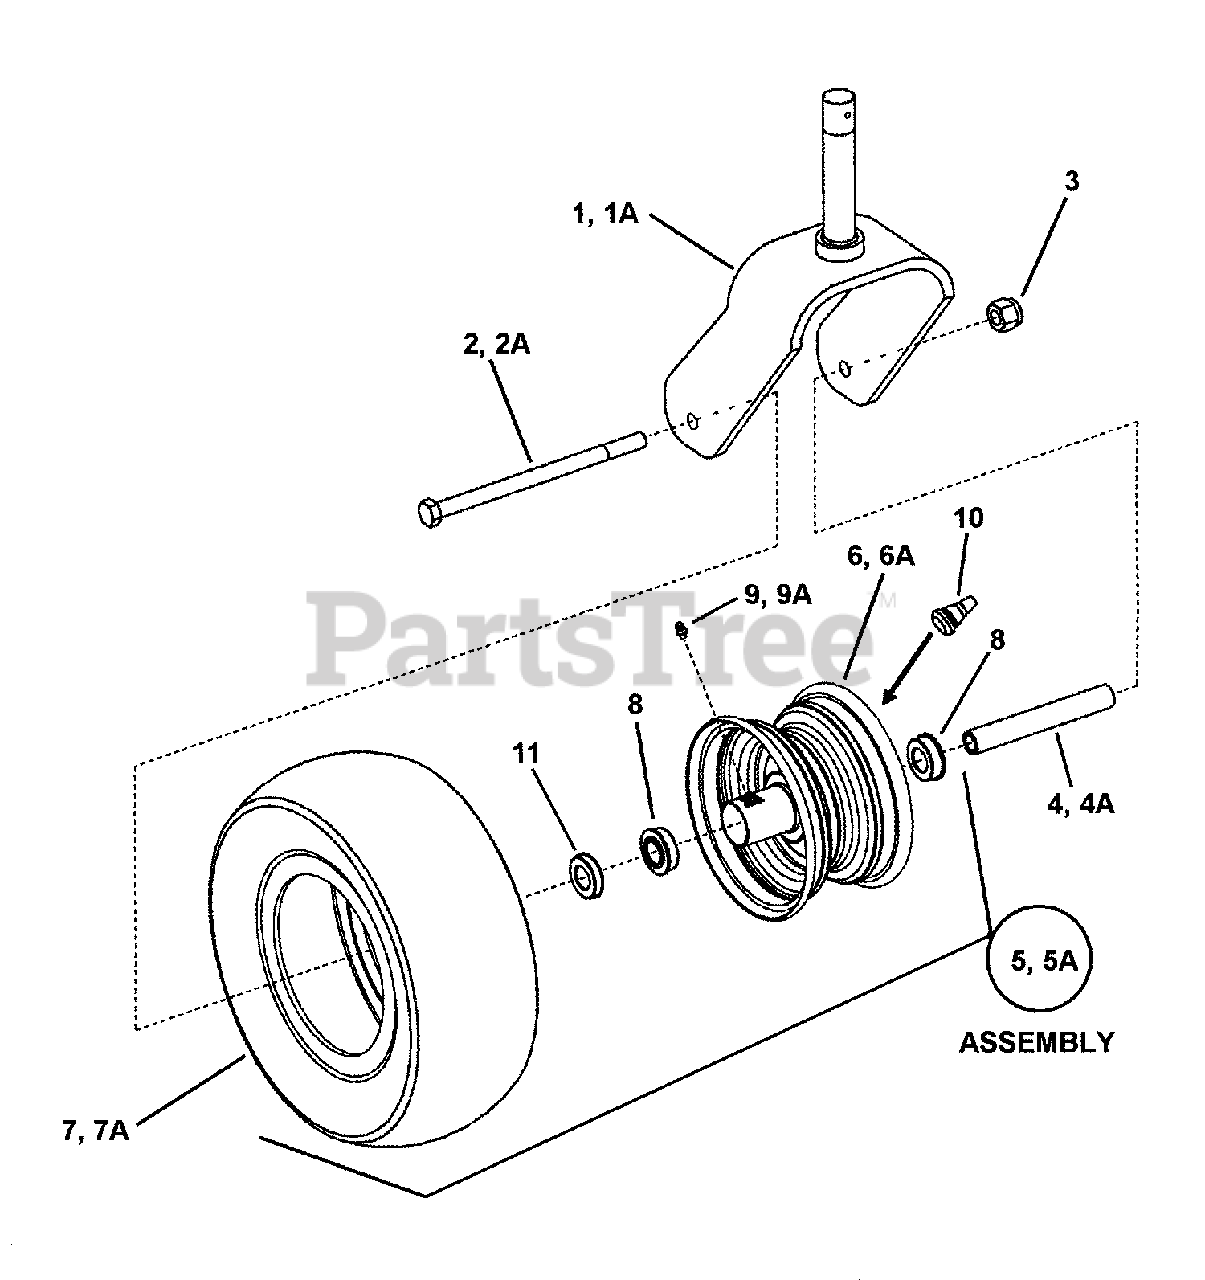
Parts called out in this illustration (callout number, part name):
1	WELDMENT, Caster Yoke
1A	WELDMENT, Caster Yoke, 7-1/4" Wide
2	BOLT, HEX, 1/2-13 X 7, GD 8, YZ
2A	SCREW, 1/2-13 x 9-1/2" Hex Head Cap, GR 5
3	NUT, 1/2-13 Hex Nyloc
4	SPACER, Bearing, 5.29" Long
4A	SPACER, Bearing, 7.29" Long
5	ASSY, Tire & Wheel 13 x 5.00-6 (Incl. item 6, 7, 8, 9 & 10)
5A	ASSY, Tire & Wheel 13 x 6.50-6 (Incl. item 6A, 7A, 8, 9 & 10)
6	WELDMENT, Wheel Hub & Rim 13 x 5.00-6 (gray)
6A	WELDMENT, Wheel Hub & Rim 13 x 6.50-6 (gray)
7	TIRE, 13 x 5.00-6 4 Ply Smooth
7A	TIRE, 13 x 6.50-6, 4PR Smooth
8	BALL BEARING, Heim .750
9	FITTING, 1/4-28 Lube
10	AIR VALVE STEM & Cap
11	SPACER
